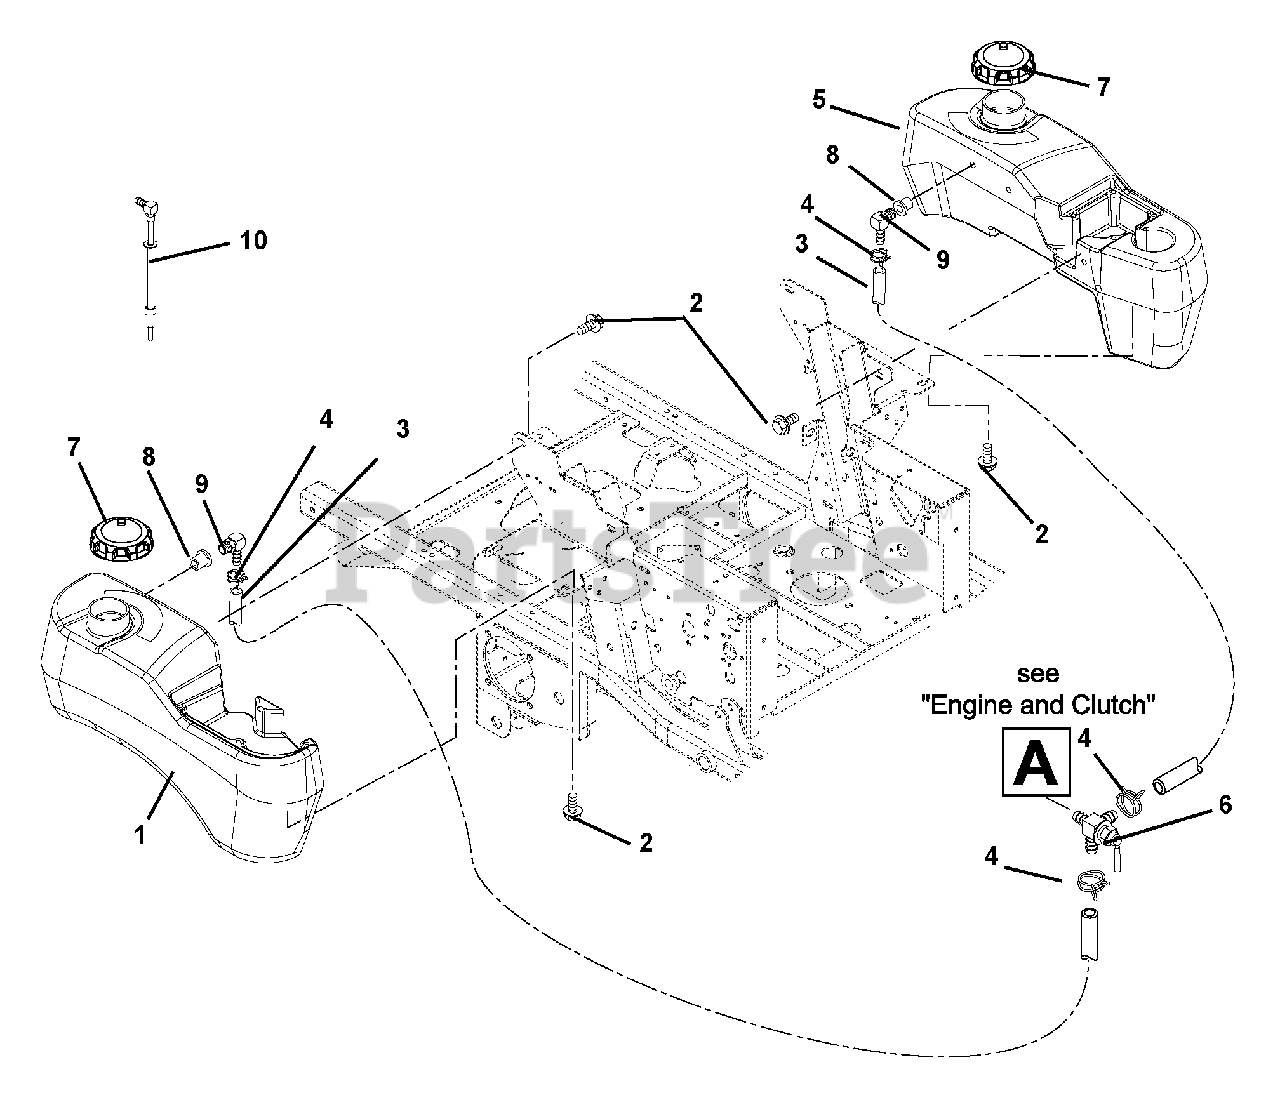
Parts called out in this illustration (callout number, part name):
1	Tank, Fuel - Right Hand
2	Bolt, SEMS .31-18 x .62
3	Gas Line, Bulk .25 I.D. (2 @ 42 in.)
4	Clamp, Hose Wire .49/.51 x .116
5	Tank, Left Hand Fuel (EYE-Q)- 200 Series
6	Valve, Fuel
7	Cap, Gas
9	Tank Fitting
10	26" Fuel Line Kit, Gas (Inside Tank)
